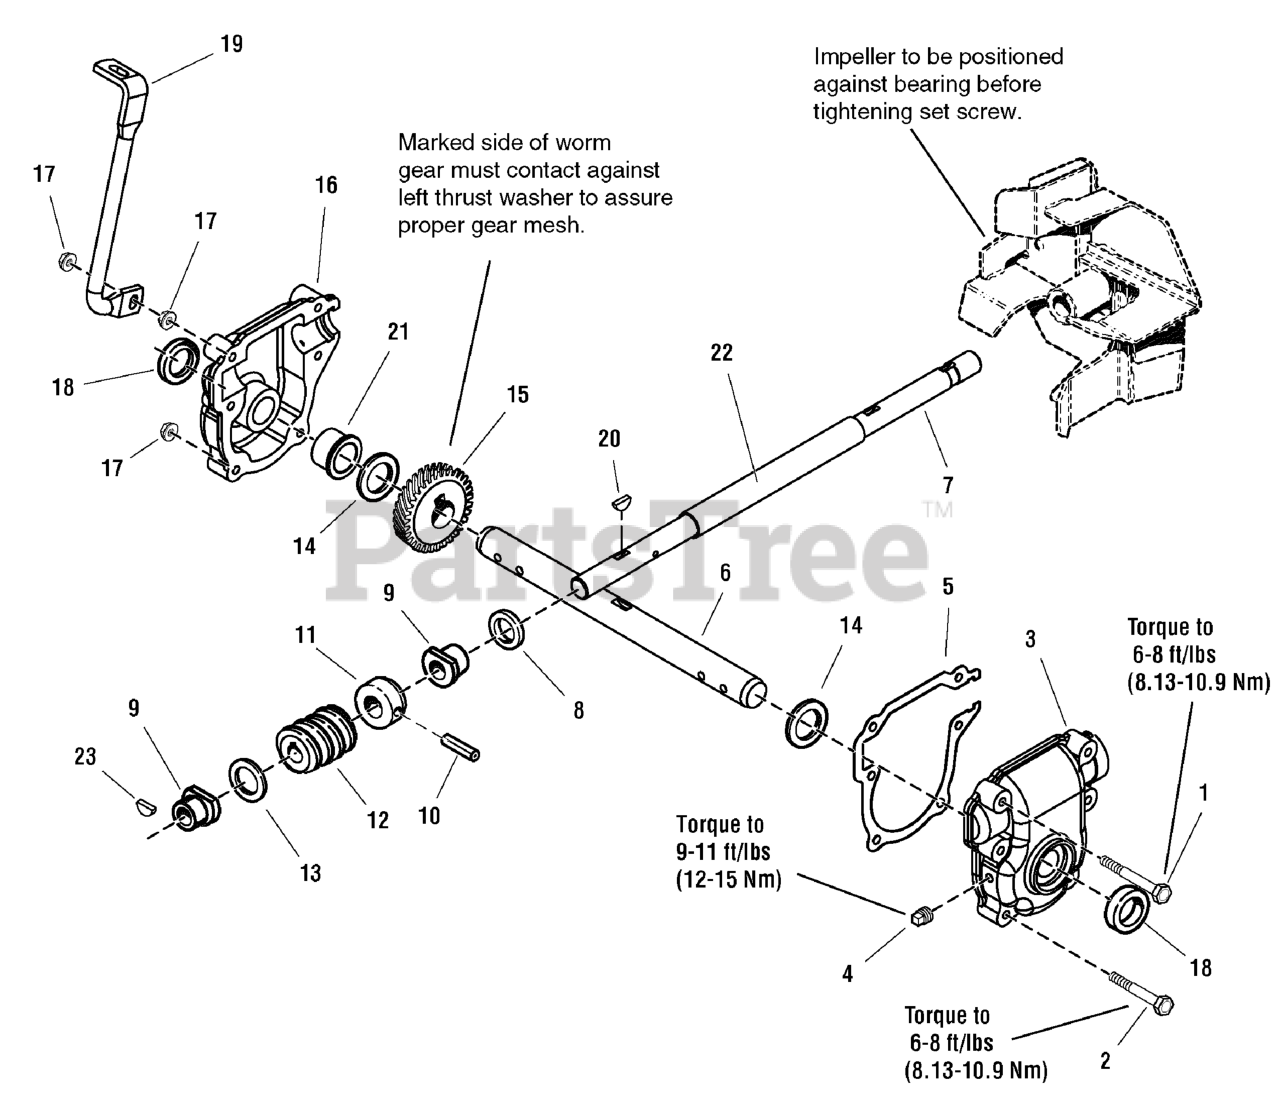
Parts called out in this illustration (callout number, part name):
1	CAPSCREW, 1/4 - 20 x 2-1/2
2	CAPSCREW, 1/4 - 20 x 2-1/4
3	GEAR CASE, L.H.
4	TAPERED PIPE PLUG
6	SHAFT, Auger Cutoff
7	SHAFT, Worm Cutoff
8	SEAL, Oil
9	FLANGE BUSHING
10	PIN, Drive Lock
11	THRUST COLLAR
12	ROLLED WORM CASE
13	THRUST WASHER
14	THRUST WASHER
15	GEAR, Worm
16	GEAR CASE, R.H.
17	NUT, Top Lock Flange, 1/4 - 20
19	WIREFORM BRACKET
20	KEY, Woodruff
23	KEY, Woodruff
